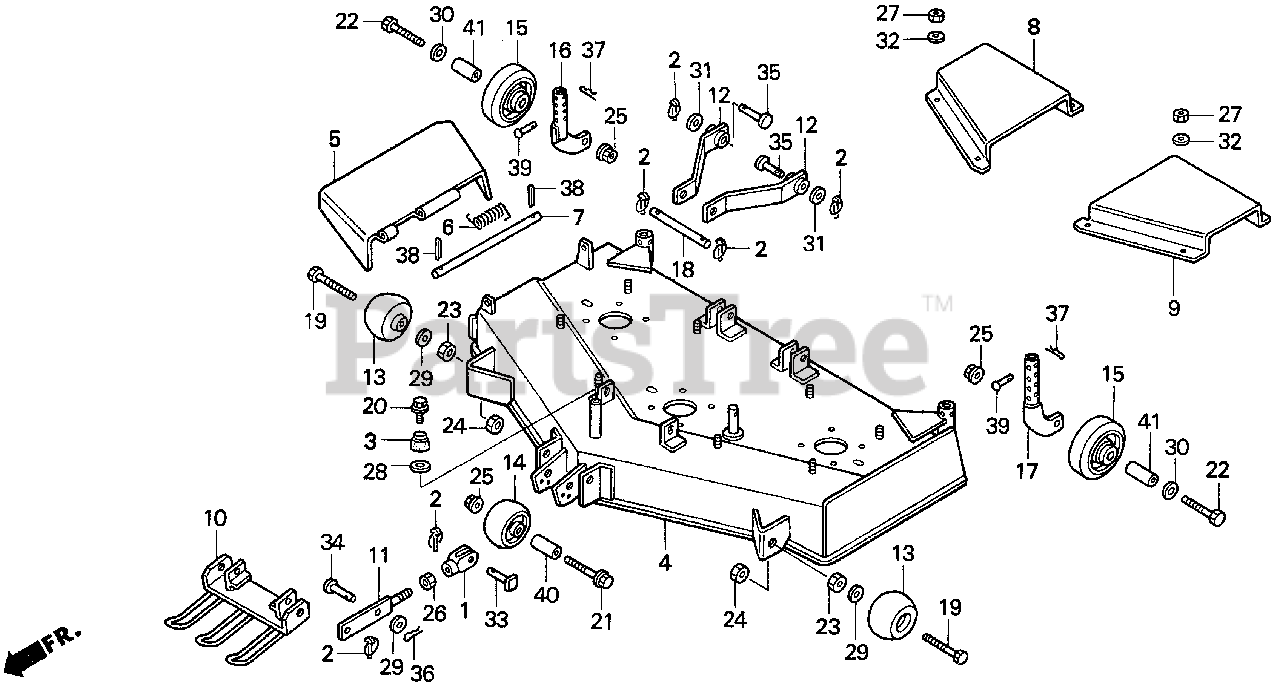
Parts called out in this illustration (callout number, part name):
1	ROD, R. ADJUSTING LIFT
2	LINCHPIN ASSY.
3	RUBBER (LOWER)
4	HOUSING, CUTTER (52") (NOT AVAILABLE)
5	ADAPTER, DISCHARGE
6	SPRING, DISCHARGE ADAPTER
7	PIN, DISCHARGE ADAPTER
8	COVER, R. BELT
9	COVER, L. BELT
10	PLATE, FR. LINK (LOWER)
11	LINK, FR. DECK
12	LINK, RR. DECK
13	ROLLER, ANTI-SCALP (SIDE)
14	ROLLER, ANTI-SCALP (CENTER)
15	ROLLER ASSY., GAUGE
16	ARM, R. GAUGE ROLLER
17	ARM, L. GAUGE ROLLER
18	SHAFT, RR. LINK
19	BOLT (1/2 NCX3-1/4 HHCS)
20	BOLT (1/4 NCX1/2 HHCS)
21	BOLT (1/2 NCX4-1/2 HHCS GR5)
22	BOLT (1/2 NCX3-1/2 HHCS GR5)
23	NUT (1/2 NC HVY HEX)
24	NUT (1/2 NC HEX. LOCK)
25	NUT (1/2 NC FLANGE LOCK)
26	NUT, HEX. (0.625 NF RH PLATED)
27	NUT (5/16 NC HEX.)
28	WASHER (40MM)
29	WASHER, SAE (1/2)
30	WASHER, STD FLAT (1/2)
31	WASHER, STD SAE (5/8)
32	WASHER, FLAT (5/16)
33	PIN, FR. LINK
34	PIN, PLATE (LOWER)
35	PIN, RR. LINK
36	PIN, LOCK (0.09X2.31)
37	PIN, SAFETY (3/32)
38	PIN, SPLIT (0.125X1)
39	PIN, GAUGE ROLLER
40	COLLAR, ANTI-SCALP ROLLER
41	COLLAR (1/2X3/4X2-1/4)
